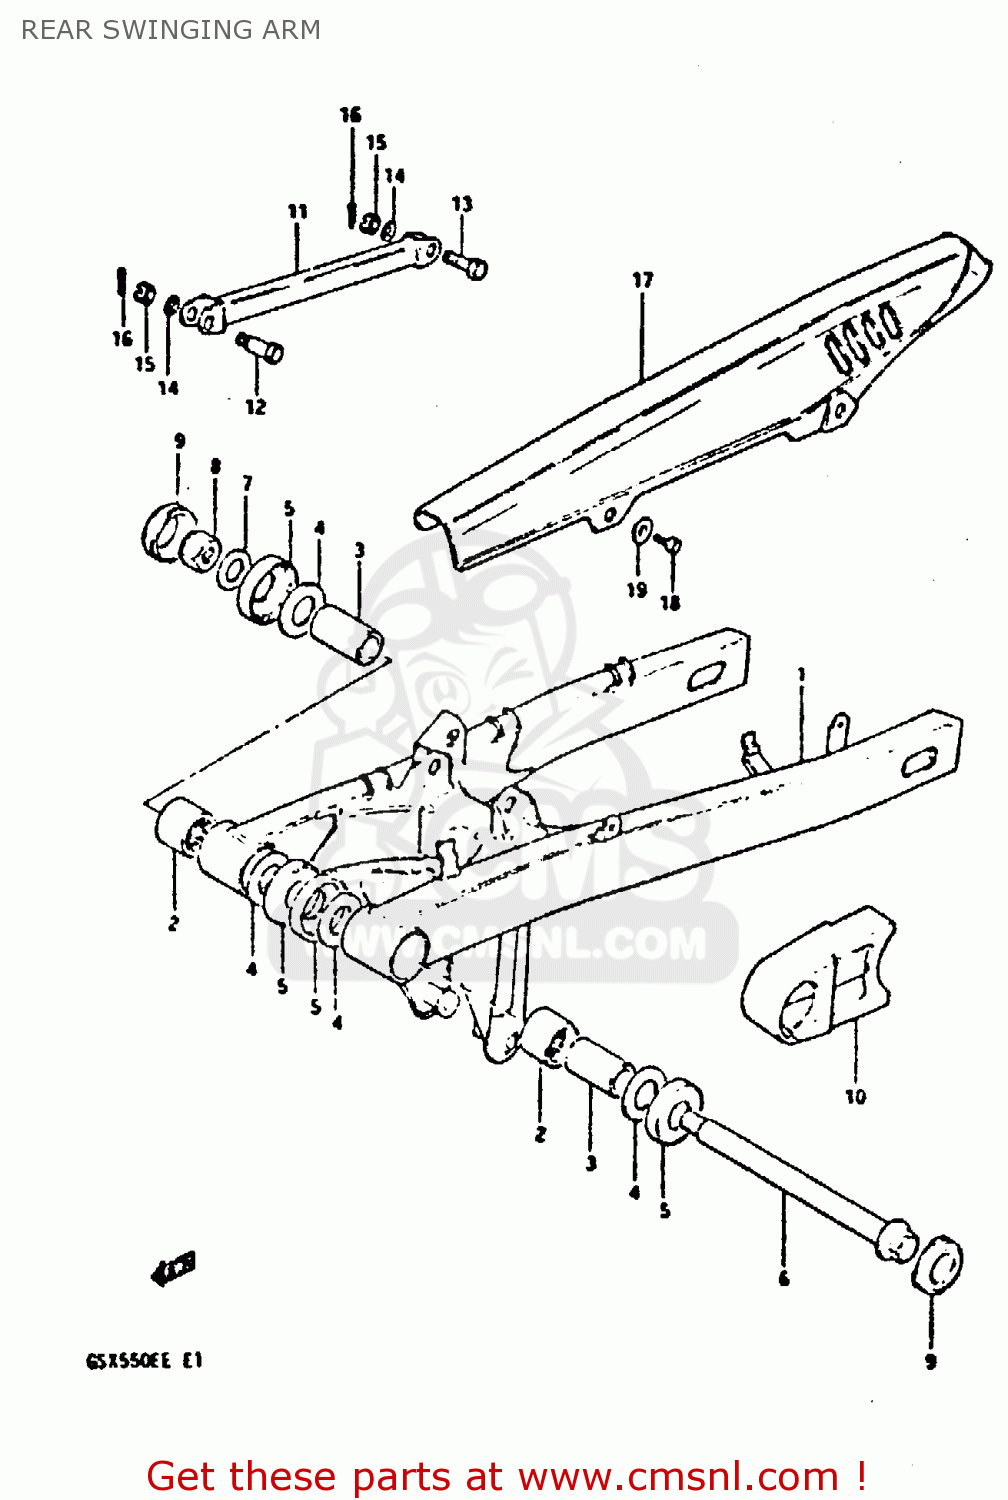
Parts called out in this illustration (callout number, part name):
1	ARM,REAR SWING
2	BEARING(25X33X30)
3	SPACER,RR SWGARM PIVOT
4	WASHER
5	COVER,RR SWGARM DUST SEAL
6	SHAFT,REAR SWING ARM
7	WASHER
8	NUT
9	CAP,SWINGINGARM PIVOT
10	BUFFER,DEFENSE
11	TORQUE LINK,REAR
12	BOLT
13	BOLT
14	WASHER
15	NUT
16	PIN 20X20
17	CASE,CHAIN
18	BOLT
19	WASHER
